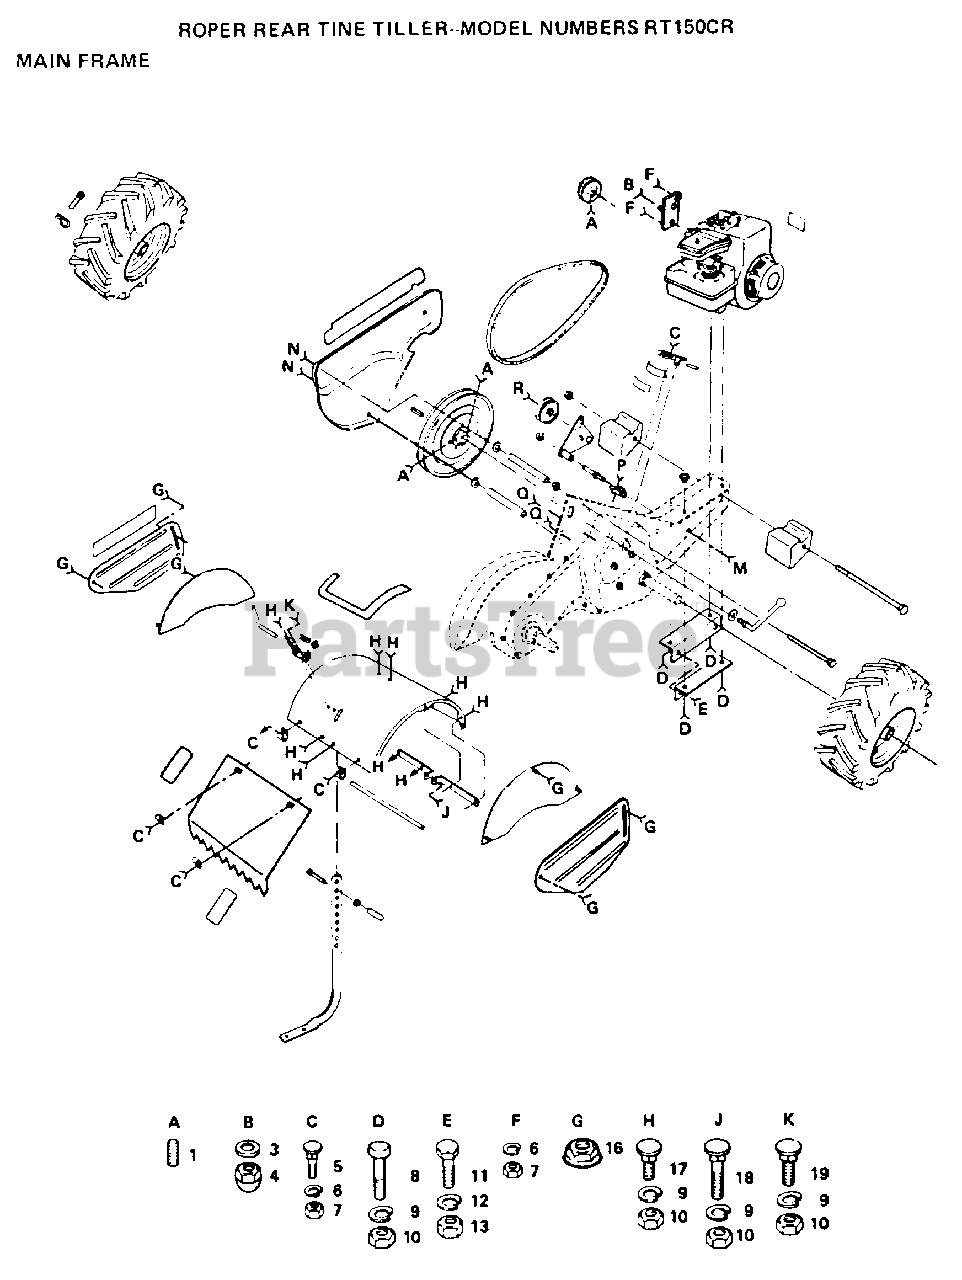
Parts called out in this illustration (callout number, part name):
1	SET SCREW
3	WASHER
4	NUT TI
5	BOLT
6	LOCKWASHER
8	BOLT.HEX.5/16-1.5
9	LOCKWASHER
10	NUT.HEX.5/16-18
11	BOLT
12	LOCKWASHER
13	NUT.HEX.3/8-16UNC
16	NUT
17	BOLT
18	BOLT CRT
19	BOLT
